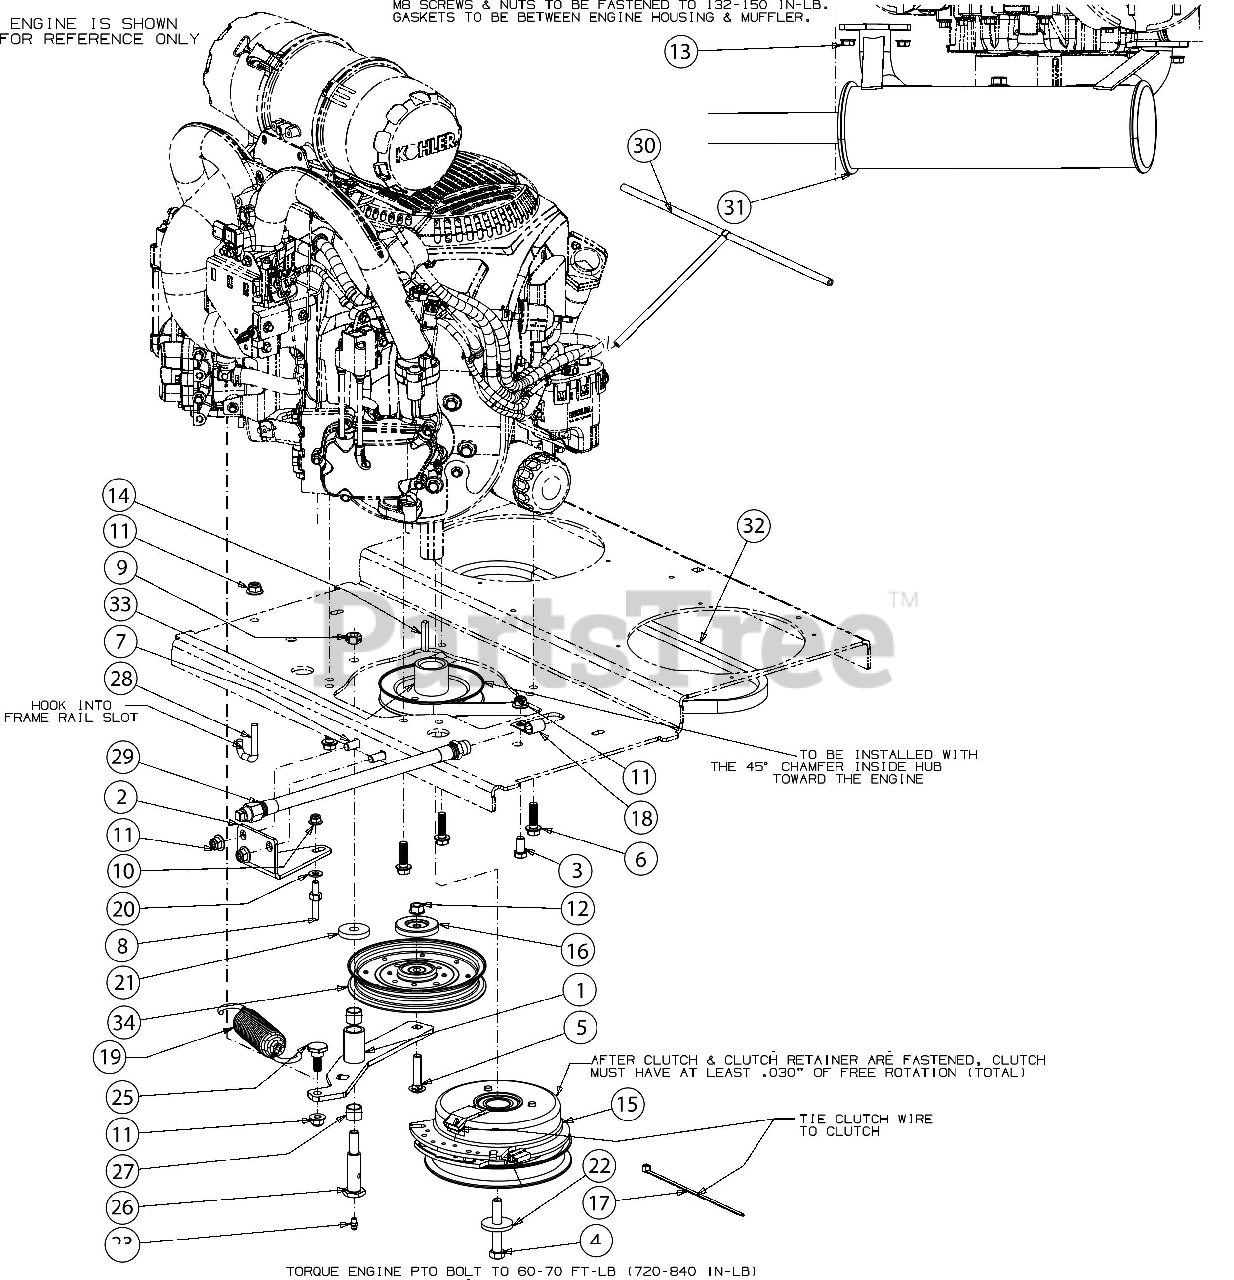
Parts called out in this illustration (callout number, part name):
1	TRANSMISSION IDLER BRACKET
2	RETAINER BRACKET
3	HEX SCREW 3/8-16 x .75
4	SCREW 7/16-20:2.75 GR5
5	CARRIAGE BOLT 3/8-16 x 1.75 GR5
6	SCREW 3/8-16 x 1.25 GR5
7	CARRIAGE BOLT 3/8-16 x 1.00 GR5
10	FLANGE LOCK NUT 5/16-18
12	HEX LOCK NUT
13	HEX FLANGE NUT
14	SQUARE KEY 1/4 x 1.50
15	ELECTRIC PTO CLUTCH
16	PULLEY CAP
17	7" CABLE TIE
18	J TYPE CLIP
19	EXTENSION SPRING W/HOOK
20	FLAT WASHER
21	FLAT WASHER 47 x 1.50 x .225
22	FLAT WASHER .45 x 1.5 x .172 HT
23	GREASE FITTING
25	SHOULDER SCREW .625 x .302 x 3/8-16
26	SHOULDER BOLT 7/16-14
27	SLEEVE BEARING
28	ROD SPRING HOOK
29	OIL DRAIN HOSE
30	ROLLOVER VENT HOSE ASSEMBLY
31	MUFFLER - KOHLER/EFI 824
32	TRANSMISSION BELT 61.5
33	DRIVE PULLEY
34	IDLER PULLEY
